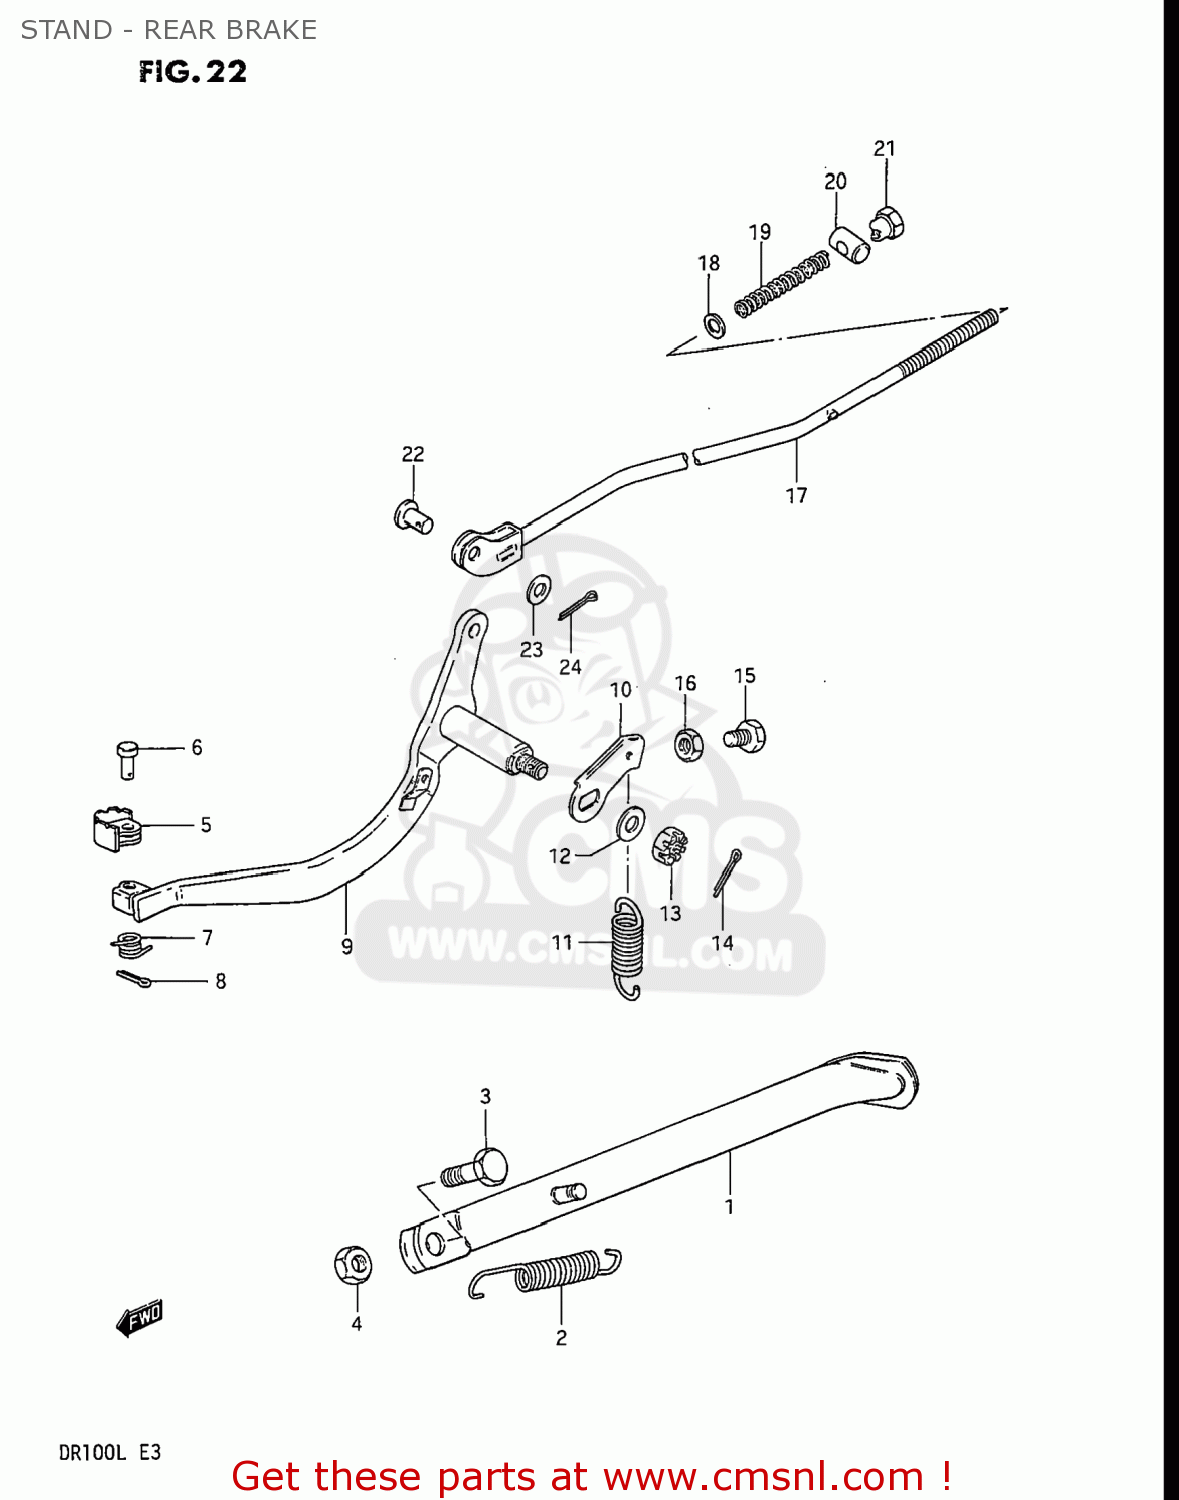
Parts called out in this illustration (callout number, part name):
1	STAND,SIDE
2	SPRING
3	BOLT(10X30)
4	NUT
5	PEDAL,BRAKE
6	PIN
7	SPRING
8	PIN
9	ARM,BRAKE PEDAL
10	ARM,BRAKE RETURN SPRING
11	SPRING
12	WASHER
13	NUT 8MM
14	PIN 20X20
16	NUT 6MM
17	ROD ASSEMBLY,REAR BRAKE
18	WASHER
19	SPRING
20	PIN(11X18)
21	NUT (6MM)
22	PIN
23	WASHER
24	PIN 20X20
